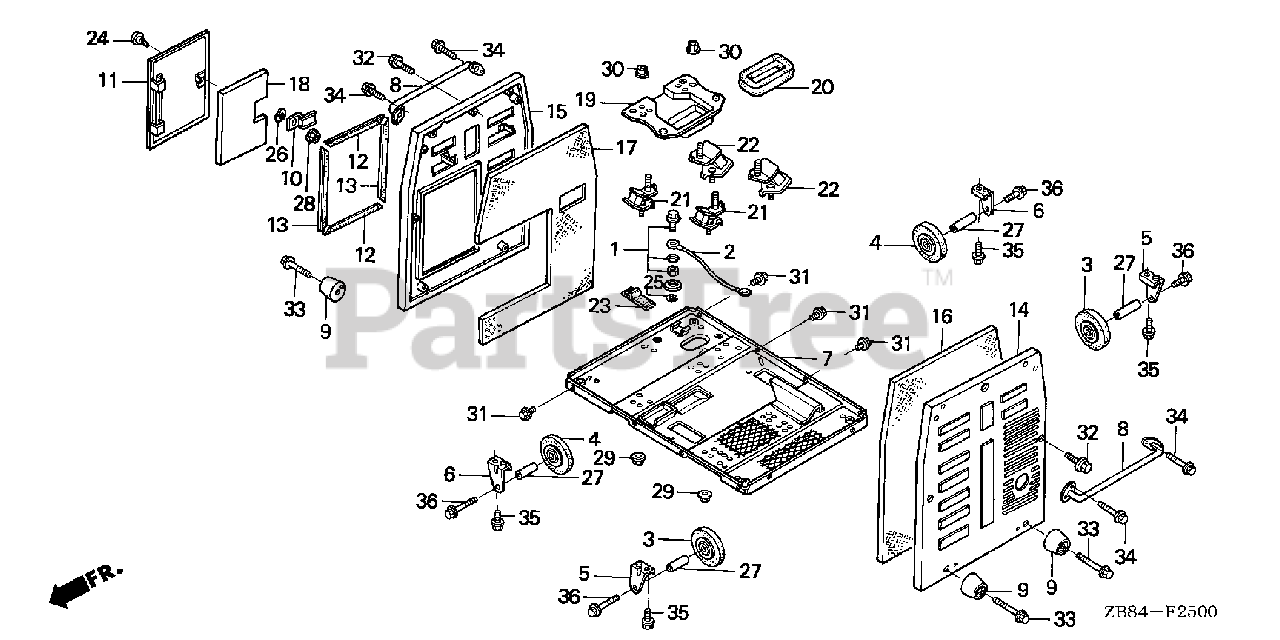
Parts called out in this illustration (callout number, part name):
1	TERMINAL ASSY., GROUND
2	CABLE, GROUND
3	WHEEL (100X33)
4	WHEEL (100X33)
5	BRACKET, R. WHEEL
6	BRACKET, L. WHEEL
7	FRAME (LOWER) *NH105* (MAT BLACK)
8	HANDLE *NH105* (MAT BLACK)
9	RUBBER (LOWER)
10	PLATE, MAINTNENANCE LID LOCK
11	LID, MAINTENANCE *NH105* (MAT BLACK)
12	SEAL C, MAINTENANCE LID
13	SEAL D, MAINTENANCE LID
14	PANEL, R. SIDE *NH105* (MAT BLACK)
15	PANEL, L. SIDE *NH105* (MAT BLACK)
16	INSULATOR, R. SIDE PANEL
17	INSULATOR, L. SIDE PANEL
18	INSULATOR, RR. MAINTENANCE LID
19	GUIDE, AIR (LOWER)
20	SEAL, AIR GUIDE (LOWER)
21	RUBBER (LOWER)
22	RUBBER (LOWER)
23	BAND, TOOL SETTING
24	BOLT, MAINTENANCE LID LOCK
25	NUT, SPECIAL (6MM)
26	WASHER, WAVE (12MM)
27	COLLAR, WHEEL SHAFT
28	NUT, FLANGE (6MM)
29	NUT, FLANGE (8MM)
30	NUT, FLANGE (10MM)
31	BOLT, FLANGE (6X12)
32	BOLT, FLANGE (6X35)
33	BOLT, FLANGE (6X35)
34	BOLT, FLANGE (6X35)
35	BOLT, FLANGE (8X16)
36	BOLT, FLANGE (8X55)
